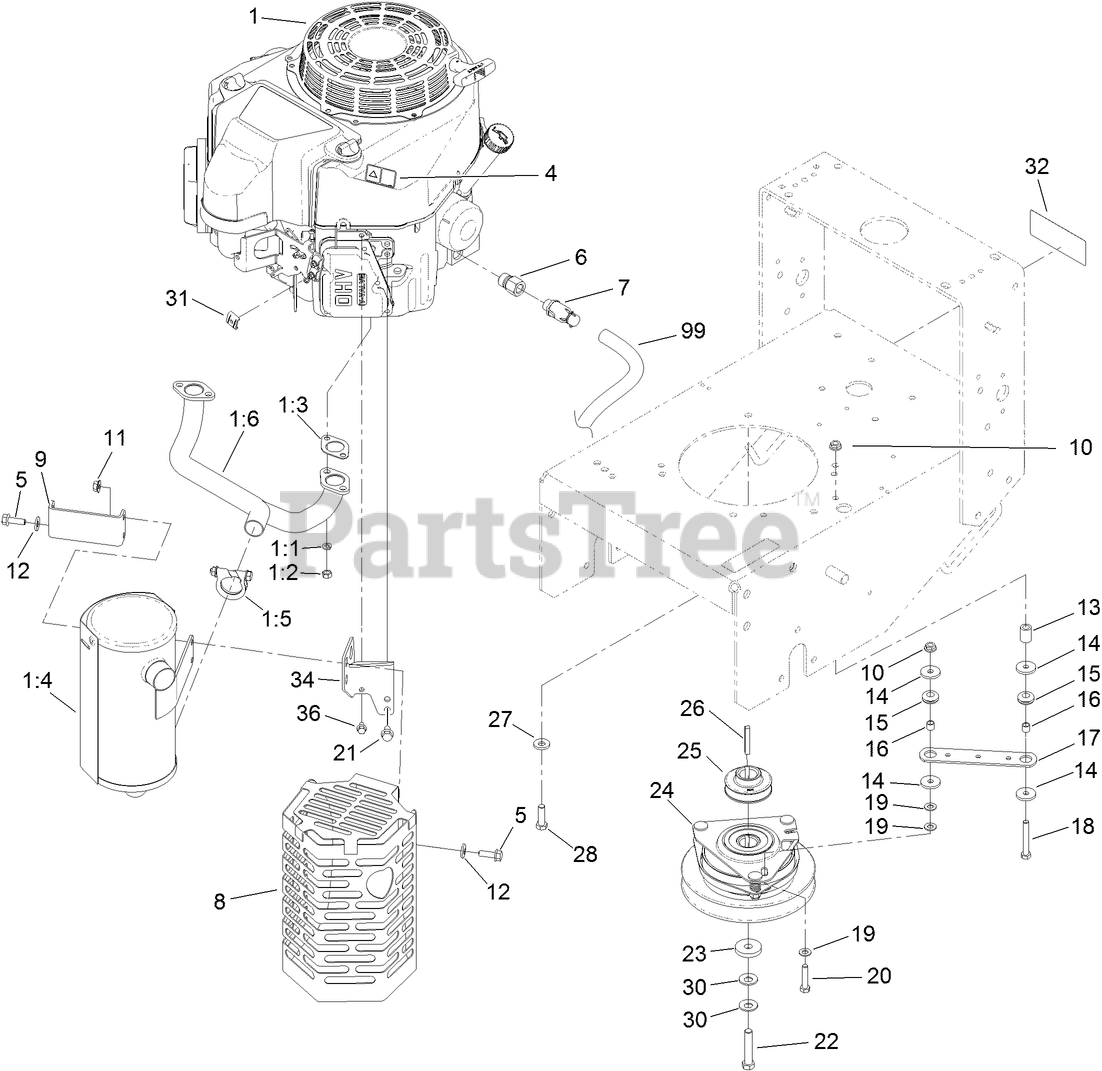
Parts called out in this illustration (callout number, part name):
1:1	WASHER-LOCK
1:3	GASKET-EXHAUST
1:4	MUFFLER-ENGINE
1:5	CLAMP-MUFFLER
1:6	MANIFOLD-EXHAUST
4	DECAL-WARNING
5	SCREW-HHF
6	Adapter
7	VALVE-DRAIN, OIL
8	SHIELD-MUFFLER
9	BRACKET-SHIELD, MUFFLER
10	NUT-HF
11	NUT-HF, LOCK
12	WASHER-SPRING
13	TUBE-RETAINER
14	WASHER
15	GROMMET
16	SPACER
17	STRAP-CLUTCH, BRAKE
18	SCREW-HH
19	WASHER-PLAIN
20	SCREW-HH
21	SCREW-HHF
22	SCREW-HH
23	WASHER
24	CLUTCH / BRAKE ASM
25	PULLEY-DRIVE
26	KEY-SQUARE
27	WASHER-BELLEVILLE
28	SCREW-HH
30	WASHER-SPRING
31	CLAMP-CABLE
32	DECAL-WARNING, SULKY
34	BRACKET-MUFFLER
36	SCREW-HHF
99	HOSE-DRAIN, OIL
